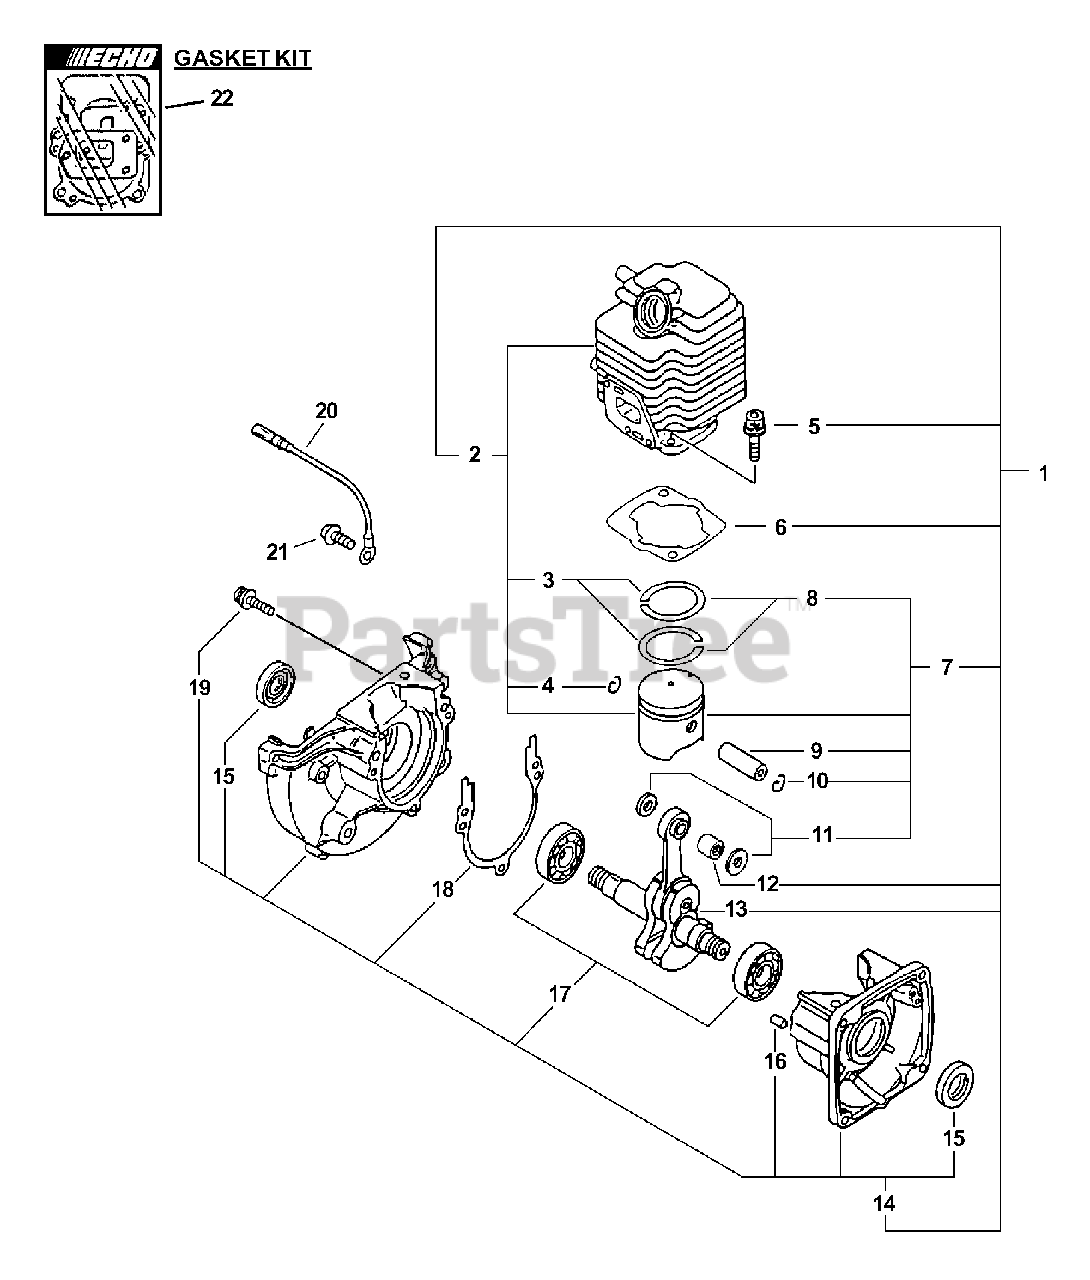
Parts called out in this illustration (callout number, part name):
1	SHORT BLOCK -- SB1027
2	CYLINDER KIT
3	RING, PISTON
4	RING, RETAINING
5	SCREW - 5X22
6	GASKET, CYLINDER
7	PISTON KIT
8	RING, PISTON
9	PIN, PISTON
10	RING, RETAINING
11	SPACER, PISTON
12	BEARING, NEEDLE
13	CRANKSHAFT ASSY
14	CRANKCASE KIT
15	SEAL, OIL
16	PIN - LOCATING
17	BEARING, BALL - 6201
18	GASKET, CRANKCASE
19	SCREW - 5X28
20	LEAD - IGNITION
21	SCREW - 4X22
22	GASKET KIT
